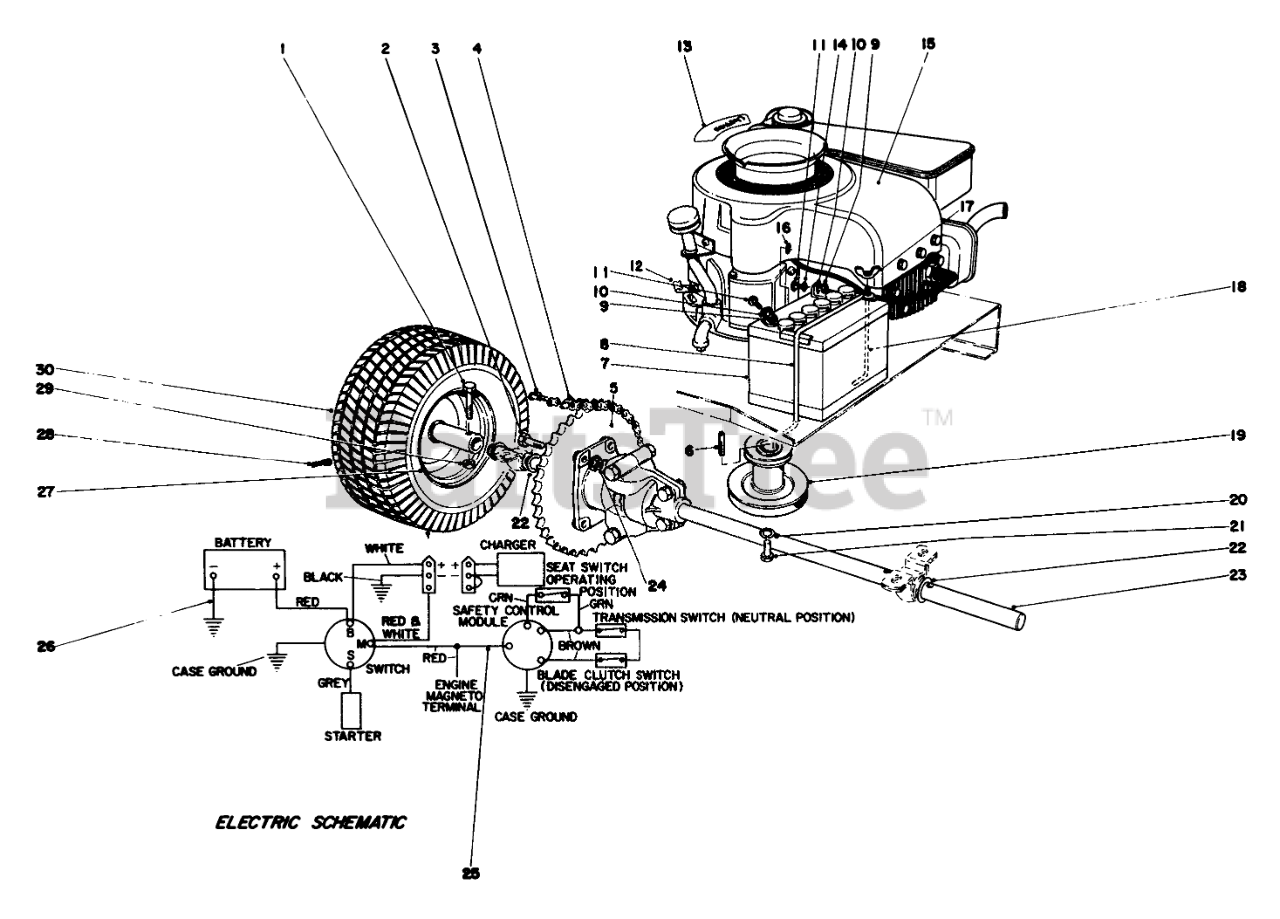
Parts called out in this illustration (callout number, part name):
1	SCREW-HH
2	SCREW-HH
3	LINK-CONNECTING
4	Chain Roller (Incl. Ref. #3)
5	Sprocket
7	BATTERY
8	Battery Clamp
9	NUT-HEX
10	WASHER-LOCK
11	SCREW-HH
13	Decal
14	WASHER-FLAT
15	Engine
16	WASHER-LOCK/EXT
17	NUT-WING SPECL
18	ROD-SUPPORT, BATTERY
19	Engine Pulley
20	WASHER-LOCK
21	SCREW-HH
22	WASHER
23	Differential
24	NUT-LOCK, CONE
25	Wiring Harness
26	ENG-GROUND WIRE ASM
28	STEM-VALVE
29	NUT-LOCK, CONE
30	Tire
